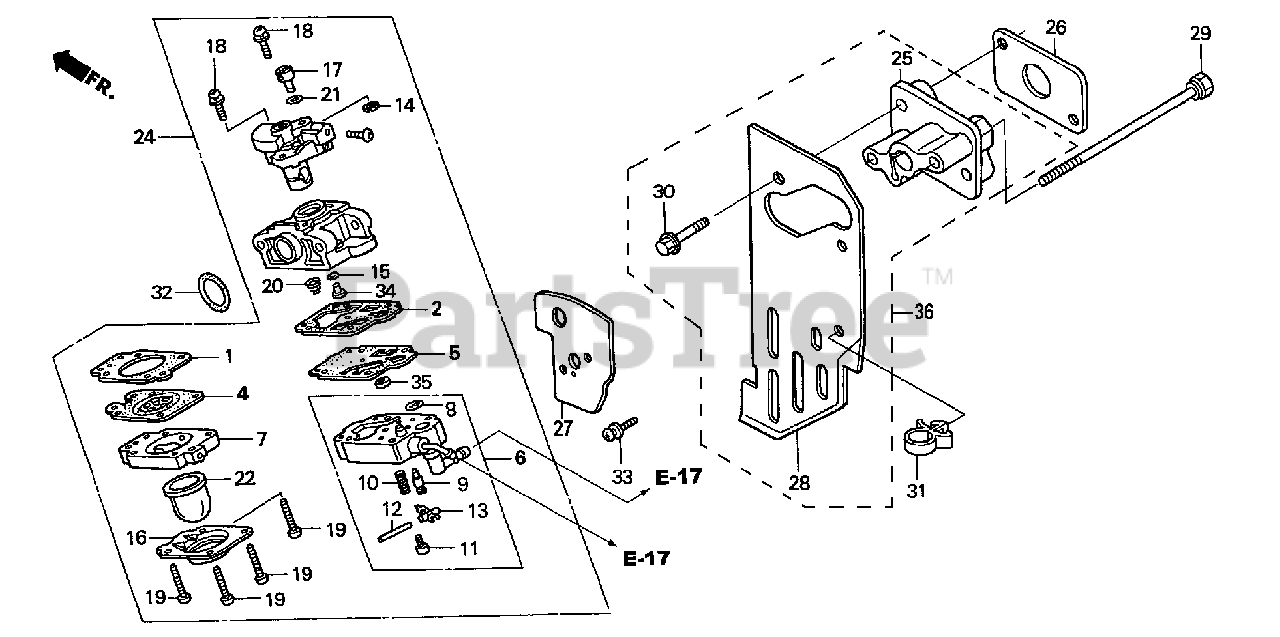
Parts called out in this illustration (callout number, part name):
1	GASKET, METERING DIAPHRAGM
2	GASKET, PUMP
4	DIAPHRAGM ASSY., METERING
5	DIAPHRAGM, PUMP
6	BODY ASSY., PUMP (CARBURETOR NO.)
7	BODY ASSY., AIR PURGE
8	SCREEN, INLET (CARBURETOR NO.)
9	VALVE, IN. NEEDLE
10	SPRING, METERING LEVER
11	SCREW, METERING LEVER PIN
12	PIN, METERING LEVER
13	LEVER, METERING
14	RING, SPRING RETAINING
16	COVER, PRIMER PUMP
18	SCREW, THROTTLE COLLAR
19	SCREW, PUMP COVER
20	SPRING, PUMP
22	PUMP, PRIMER
24	CARBURETOR ASSY. (WYL 127)
24	CARBURETOR ASSY. (WYL 127A)
25	INSULATOR, CARBURETOR
26	GASKET, INSULATOR
27	GASKET, CARBURETOR
28	GUIDE, AIR IN.
29	BOLT, HEX. (5X75)
30	BOLT, FLANGE (5X32)
31	CLIP, WIRE HARNESS
32	O-RING (14.8X2.4)
33	SCREW-WASHER (5X10)
34	JET (#33.5) (CARBURETOR NO.)
34	JET (#34.5) (CARBURETOR NO.)
34	JET (#35.5) (CARBURETOR NO.)
35	FILTER, FUEL INLET (CARBURETOR NO.)
